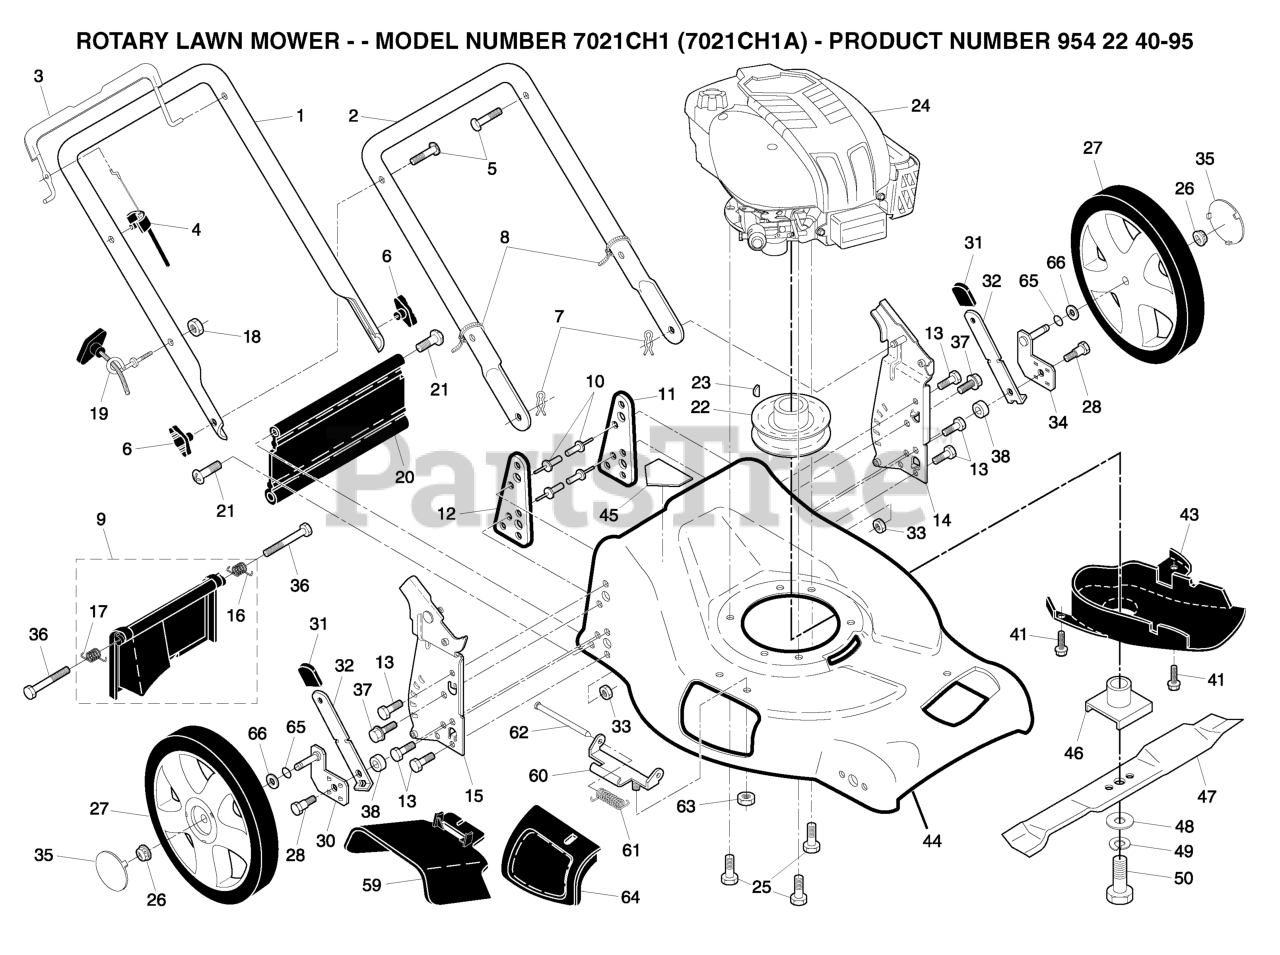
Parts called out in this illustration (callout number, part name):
2	LOWER HANDLE
4	ENGINE ZONE CONTROL CABLE
5	HANDLE BOLT
7	HAIRPIN COTTER
8	TIE GUIDE
9	KIT.DOOR.RR.ASM.21.FWGD
10	RIVET BLIND
11	SUPPORT BRACKET LH
12	SUPPORT BRACKET RH
13	SCREW 14-20 X 5/8
14	HANDLE BRACKET ASSEMBLY, LEFT
15	HANDLE BRACKET ASSY. (RIGHT)
17	SPRING.REAR.DOOR.EZ.21
18	NUT
19	ROPE, GUIDE
21	HINGE SCREW
22	PULLEY.ENG.25MMM
23	HI-PRO KEY
25	BOLT 3/8-16X1-1/8
26	HEX FLANGE LOCKNT
27	RP WHEEL 14X2
28	SHOULDER BOLT
30	AXLE ARM ASSEMBLY RR
32	SELECTOR SPRING
33	NUT.71038.31-18.HEX.NYLOCK
34	AXLE ARM ASSEMBLY LR
35	HUBCAP
37	SELF-TAPPING SCREW 5/16-18X3/4
38	SPACER.34X1.38X.22
41	SCREW.HEX.WSH
43	BOTTOM BELT COVER
45	DECAL HYT
46	BLADE ADAPTER
47	BLADE
48	WASHER,HARDEN
49	LOCKWASHER
50	SCREW, HEX HD 3/8-24 X 1-3/8
59	DEFLECTOR.CLIPPIN.21.FGD
60	BRACKET.ASM.HINGE.21.FWGD.
61	SPRING
62	ROD.HINGE.21
63	LOCKNUT.NYLOC.1/4-20
64	DOOR.MULCH.21.REAR.FWGD
65	O-RING
66	WASHER.FLAT.1/2
